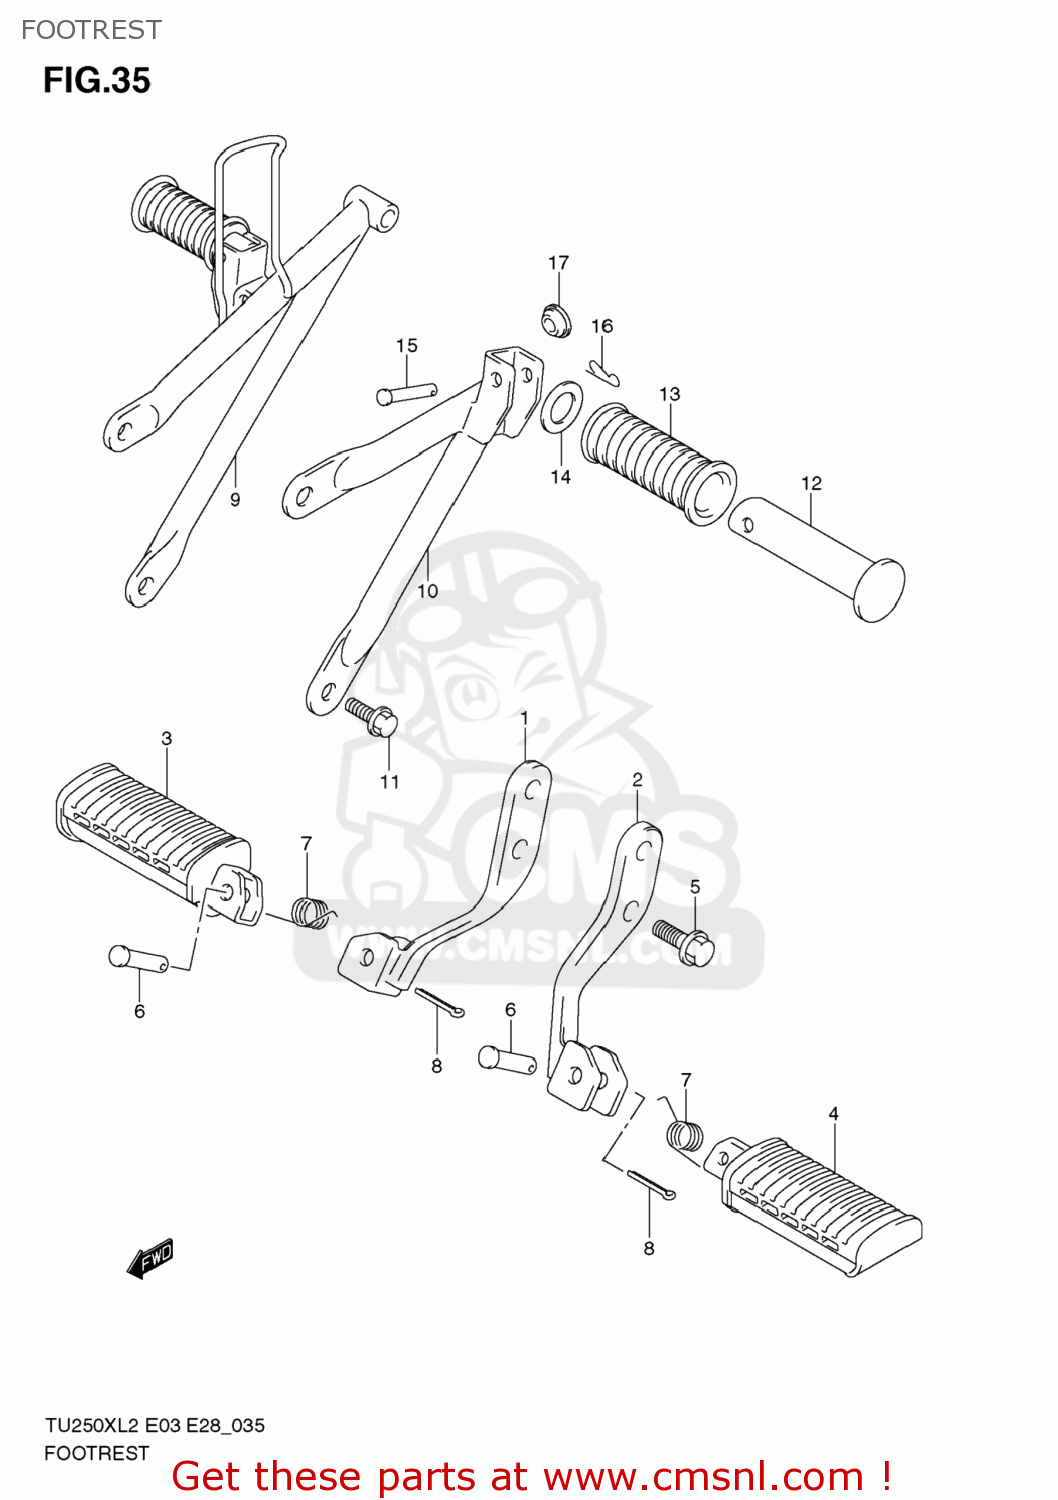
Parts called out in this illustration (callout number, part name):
1	BAR,FR FOOTREST,R
2	BAR,FR FOOTREST,L
3	RUBBER,PILLION FOOTREST,R
4	RUBBER,PILLION FOOTREST,L
5	BOLT
6	PIN
7	SPRING
8	PIN
9	TUBE,PILLION FOOTREST,R(BLACK)
10	TUBE,PILLION FOOTREST,L(BLACK)
11	BOLT
12	BAR,FOOTREST RUBBER
13	RUBBER,PILLION FOOTREST
14	WASHER(19.5X32X2)
15	PIN
16	CLIP
17	PLUG(OD:19)
